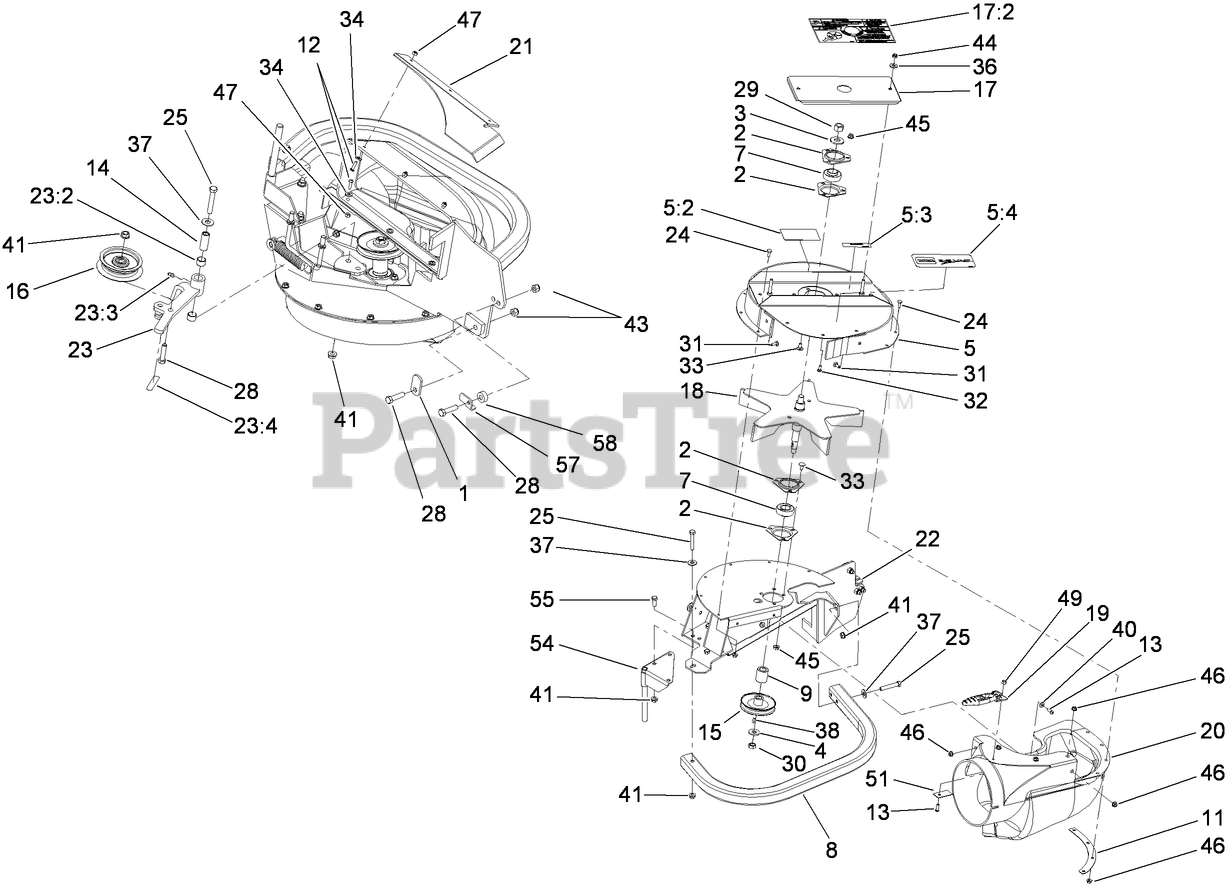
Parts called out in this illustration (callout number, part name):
1	LATCH-CATCHER, GRASS
2	HOUSING-FLANGE
3	WASHER-SPRING
4	WASHER-SPRING
5	UPPER HOUSING ASM
5:2	DECAL-WARNING
5:3	DECAL-COVER, MISSING
7	BEARING
9	SPACER
11	PLATE-BACKING, BLOWER
12	SCREW-HSBH
13	SCREW-HSBH
14	BUSHING
15	SHEAVE
16	IDLER-FLAT
17	COVER-BEARING
17:2	DECAL- BLOWER WARNING
18	IMPELLER
19	LATCH-RUBBER
20	CHUTE-BLOWER
21	PLATE-BOTTOM
22	BLOWER MOUNT ASM
23	IDLER ARM ASM
23:2	BUSHING
23:3	FITTING-GREASE
23:4	DECAL-WARNING
24	SCREW-HH
25	SCREW-HH
28	SCREW-HH
29	NUT-HEX
30	NUT-JAM
31	BOLT-CARR
32	SCREW-CARR
33	SCREW-CARR
34	WASHER-FLAT
36	WASHER-FLAT
37	WASHER-FLAT
38	KEY-WOODRUFF
40	WASHER-FLAT
41	NUT-HHF, WHIZ
43	NUT-LOCK, NI
44	NUT-LOCK, NI
45	NUT-HF
46	NUT-HF
47	NUT-LOCK, NI
49	NUT-LOCK, NI
51	PLATE-BACKING
54	PIN-MOUNT
55	SCREW-HH
57	LATCH-STOP
58	SPACER
